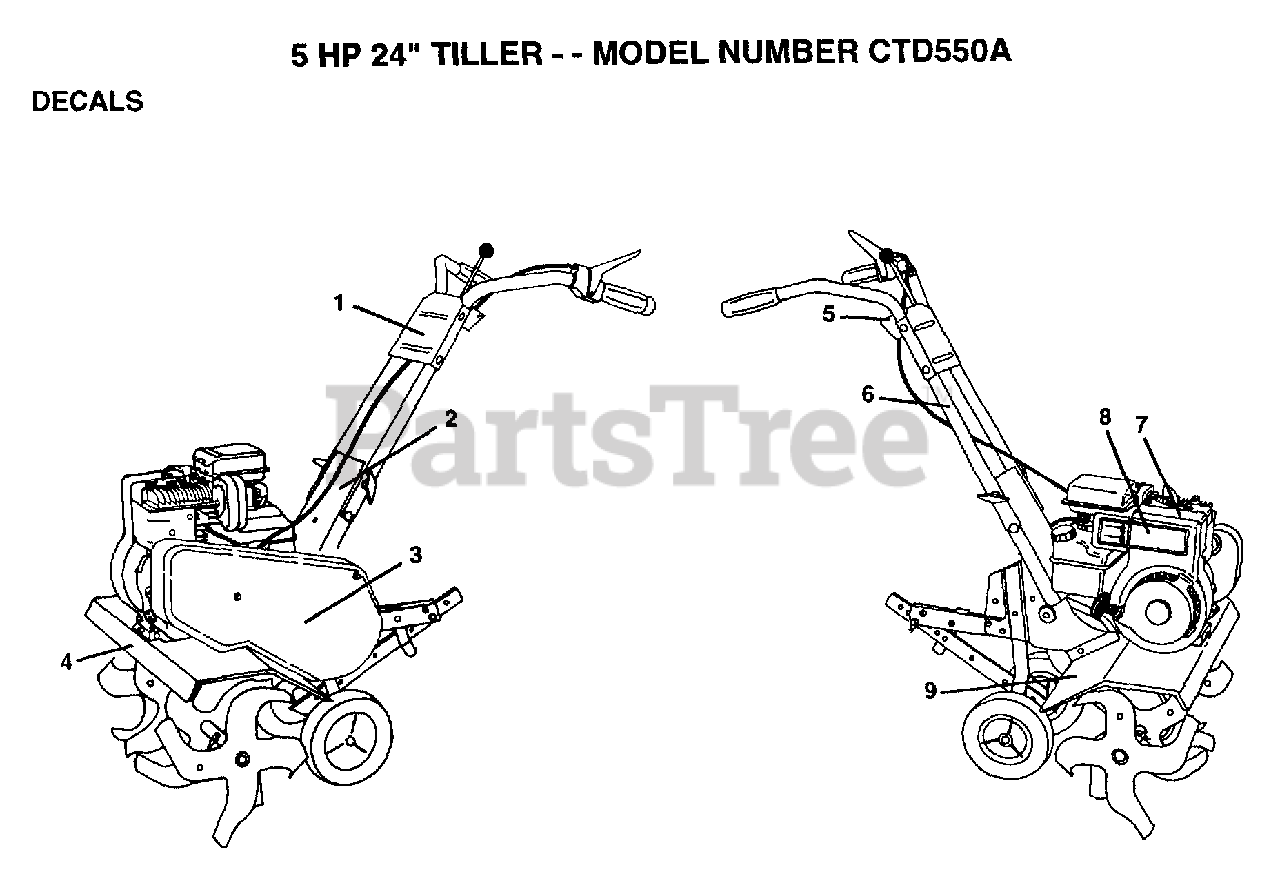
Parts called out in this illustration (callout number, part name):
1	DECAL PNL CNTL
3	DECAL GUARD BELT
4	DECAL TINE SHIELD
5	DECAL REVERSE
6	DECAL TI
9	DECAL TI
